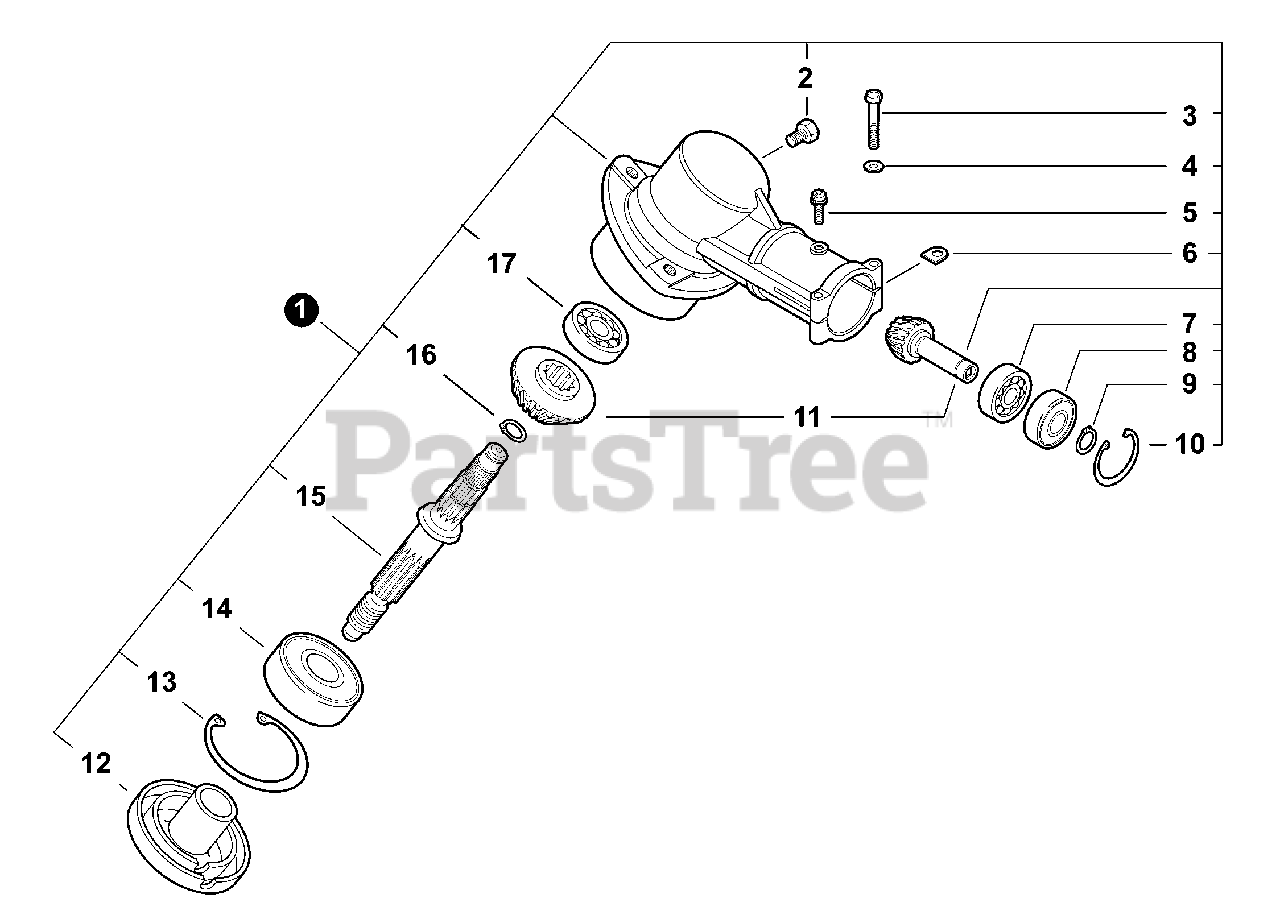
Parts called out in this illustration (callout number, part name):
1	GEAR CASE ASSY
2	BOLT - 8×8
3	SCREW - 5×25
5	SCREW - 5×10
6	WASHER, SHIM
7	BEARING, BALL - 6900
8	BEARING, BALL - 6900Z
9	RING, RETAINING - 10
10	RING, RETAINING - 22
11	GEAR SET - BEVEL
12	ADAPTER, BLADE - UPPER
13	RING, RETAINING - 32
15	BEARING, BALL - 6201
16	GEAR, SHAFT
17	RING, RETAINING - 12
